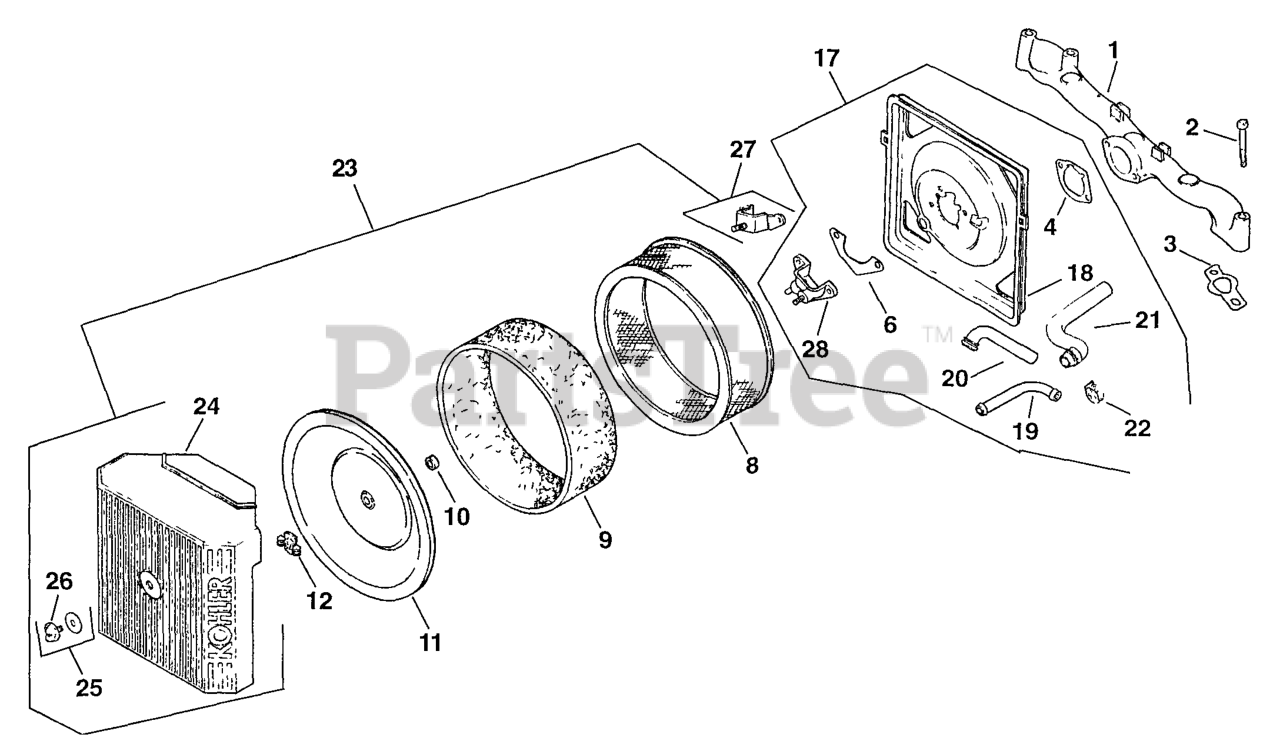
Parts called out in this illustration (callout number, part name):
1	MANIFOLD, INTAKE
2	Screw, hex. flange M6x1.0x55
3	GASKET, INTAKE MANIFOLD USE 24 041 79-S
4	GASKET, AIR CLEANER BASE
6	GASKET, FUEL SPITBACK CUP
8	ELEMENT, AIR CLEANER - Also available Retail Packaged 47 883 03-S1 Air Filter Kit
9	ELEMENT, PRECLEANER (LOW)
10	SEAL, INNER AIR CLEANER
11	COVER, INNER AIR CLEANER
12	NUT, WING
17	KIT, AIR CLEANER BASE
18	BASE - USE 24 094 19
20	HOSE, BREATHER-USE 24 326 86-S
21	HOSE, BREATHER-USE 24 326 87-S
22	CLAMP, HOSE 1/2" USE 25 237 14-S
23	KIT, AIR CLEANER COVER
25	KIT - USE 54 755 01
26	KNOB - USE 25 341 03
28	CUP - USE 24 109 10
